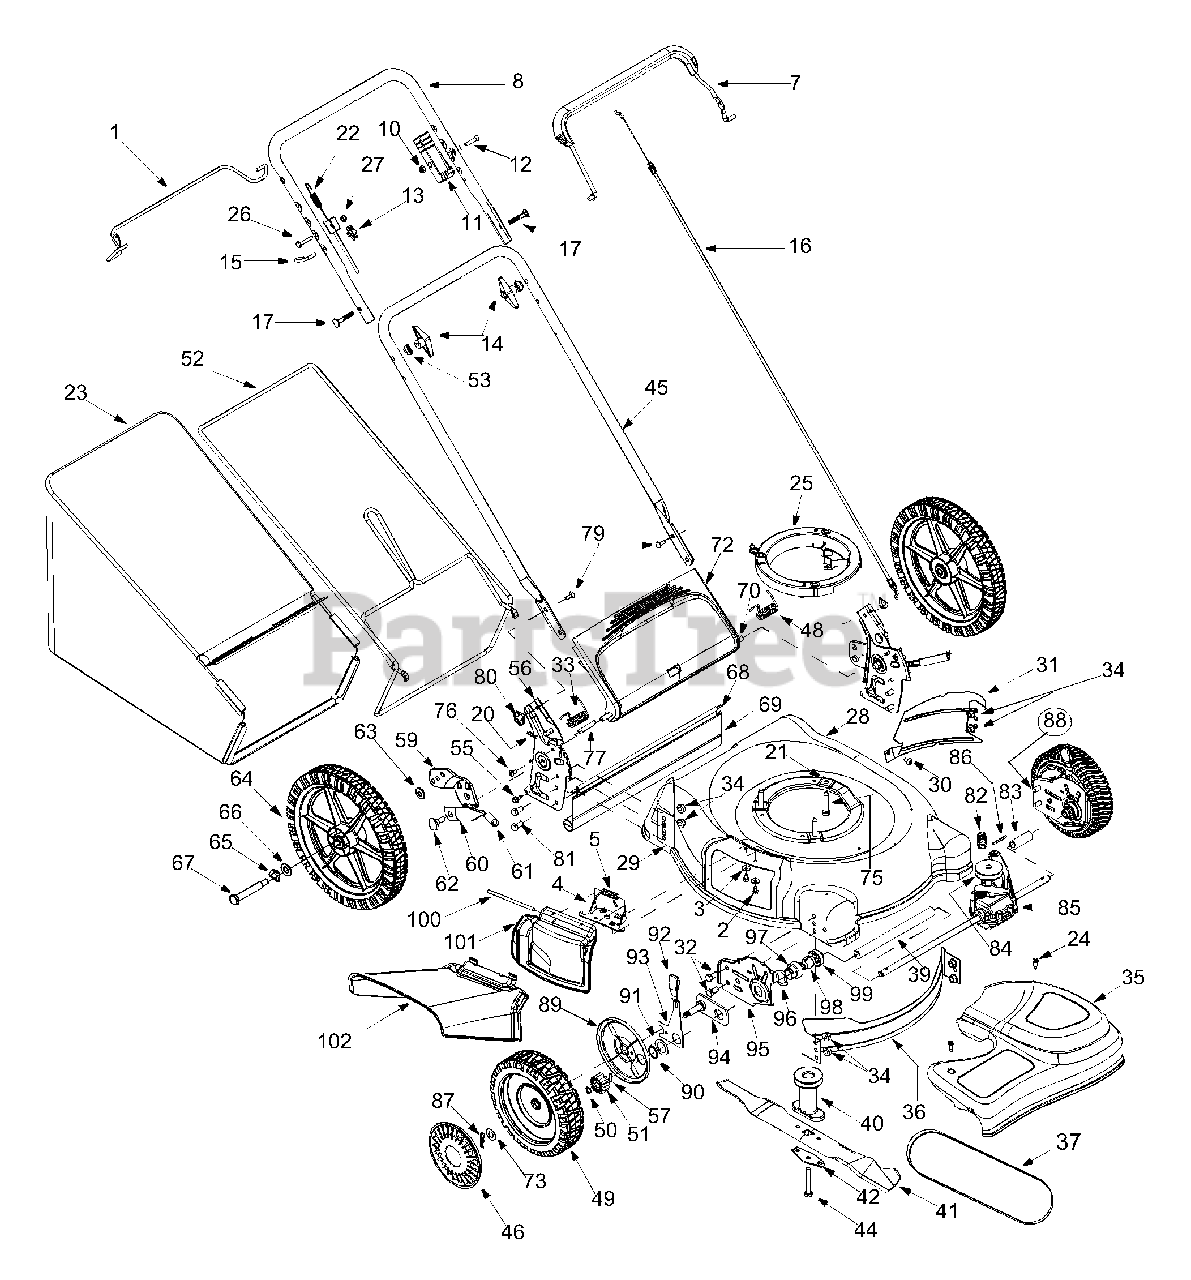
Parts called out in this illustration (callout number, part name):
2	TT Screw 1/4-20 x 0.5
3	Bell Washer .265 x 0.75
5	Torsion Spring
7	Control Lever
11	Throttle Housing
12	Oval C-Sunk Screw 1/4-20 x 1.31
13	Handle Knob
14	Handle Knob
15	Eye Bolt
16	Control Cable: 40.5"
16	Control Cable: 55"
17	Carriage Bolt 5/16-18 x 2.0
20	Cotter Pin
21	Self-Tapping Sems Screw
22	Drive Cable
23	Grassbag Assembly
24	Shoulder Screw # 12 -24
25	Engine Spacer
26	Hex Bolt 1/4-20 x 1.5
27	Lock Nut 1/4-20
28	21" Deck
30	Screw AB: 1/4-14: .625
32	Hex Screw 3/8-16 x .75
33	Torsion Spring
34	Hex Nut 3/8-16
35	Transmission Cover (Yellow)
39	Axle: Front
40	Blade Adapter w/ Pulley
41	21" Mulching Blade
42	Blade Bell Support
44	Hex Screw 3/8-24 x 2.50
46	Hub Cap
48	Torsion Spring
49	Wheel 8 x 2
50	Snap Ring
51	Gear 14T LH FWD
53	Saddle Washer
55	Hex Scr. w/Washer 1/4-14 x .625
56	RH Handle Bracket
56	LH Handle Bracket
57	Dowel Pin
59	RH Pivot Bar
60	Height Adj. Lever
61	Foam Grip
62	Shoulder Scr .500 Dia. x .434
63	Washer .401 x .870 x .063
64	Wheel, 14 x 2.125
65	Spring Washer .50 I.D. x 1.0 O.D.
66	Flat Washer
67	Shoulder Screw
68	Wire
69	Rear Trailing Shield
70	Pivot Rod
72	Rear Discharge Door
73	Flat Washer
75	Shoulder Screw
76	Machine Screw
77	Spacer .375 x .50 x 1.02" Lg.
79	Carriage Bolt 1/4-20
80	Wing Nut
81	Hex Bolt 3/8-16 x 1.0"
82	Belt Tension Spring
83	Slev. Spacer RH
84	Input Pulley
85	Transmission Assembly
86	Roll Pin
87	Hairpin Clip
88	Height Adjustment Assembly RH
89	Wheel Dust Cap
90	Snap Ring
91	Washer
92	Adjustment Knob
93	Front Lever RH
94	Pivot Plate Assembly
97	Bearing Support
98	Bearing Sleeve
99	Bearing Retainer
100	Hinge Pin
101	Mulch Plug Comp.
102	Chute Deflector
